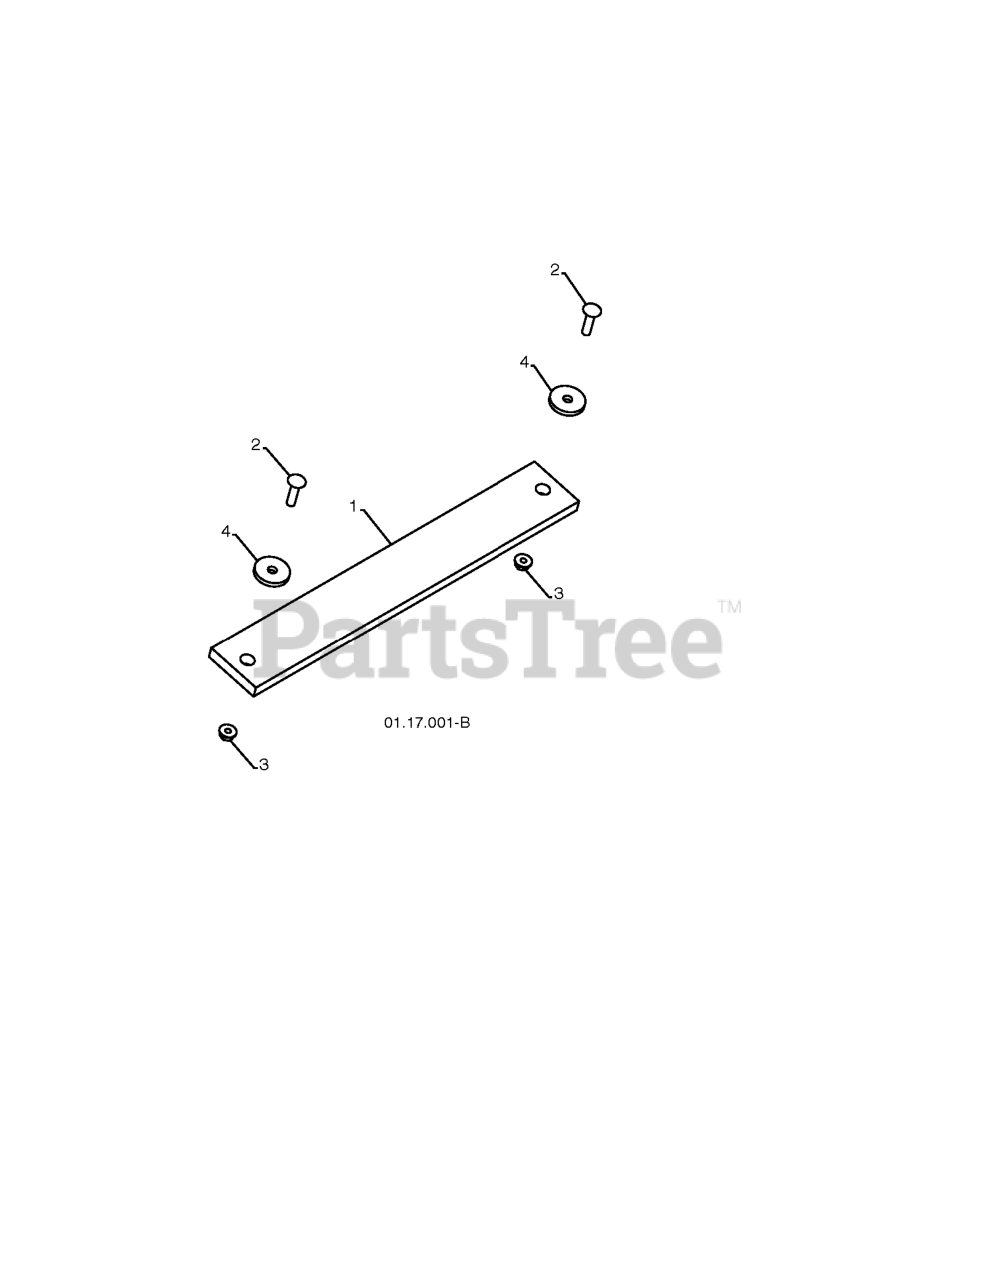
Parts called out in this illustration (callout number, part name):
1	WEIGHT.AUGER.HSG.24
2	BOLT.CARRIAGE.5/16-18
3	NUT.LOCK.5/16-18
4	WASHER.FLAT.34X1.38X22
